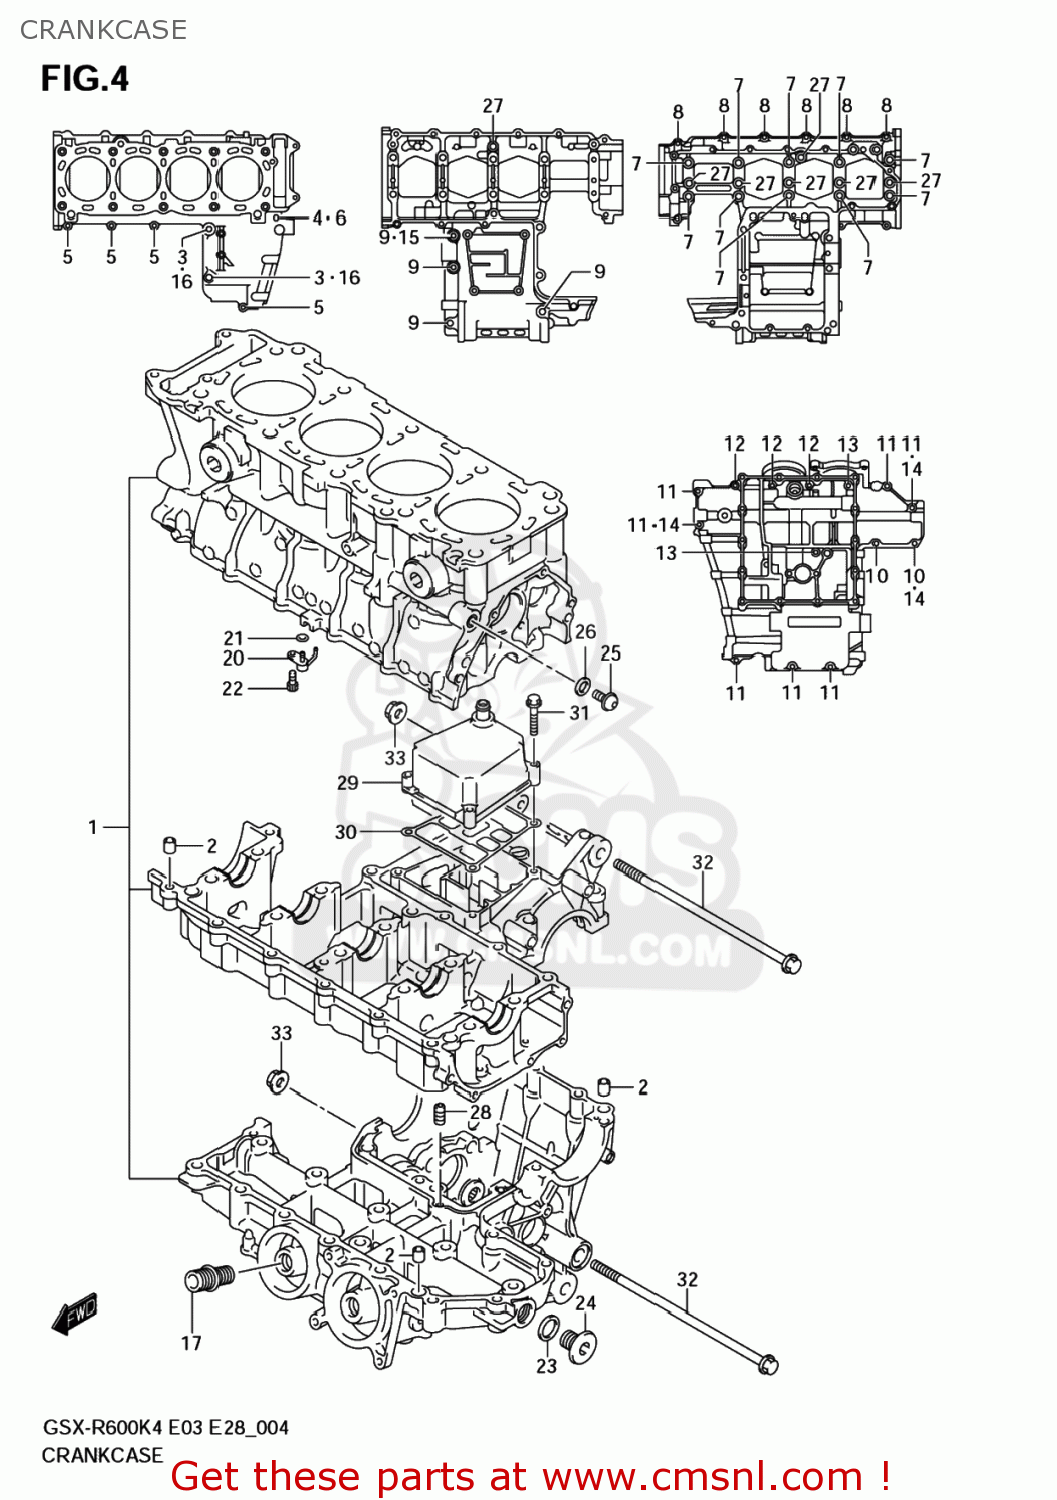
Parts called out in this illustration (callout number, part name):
1	CRANKCASE SET
2	PIN,CRANKCASE
3	BOLT(8X120)
4	GASKET(5.8X13X1.2) (NAS)
5	BOLT
6	BOLT
7	BOLT(9X95)
8	BOLT
9	BOLT
10	BOLT,G/S SWITC
11	BOLT
12	BOLT
13	BOLT
14	GASKET(5.8X13X1.2) (NAS)
15	GASKET(8.2X14X1) (NAS)
16	GASKET(8.2X14X1) (NAS)
17	UNION,OIL STAND
18	BEARING,CRANK THRUST(GREEN)
19	BEARING,CRANK THRUST(RED)
20	JET,PISTON COOLING
21	O RING(D:1.2,ID:4)
22	BOLT(6X12)
23	GASKET(16X22X2) (NAS)
24	PLUG
25	PLUG(10X10)
26	GASKET(10X14X3.6) (NAS)
27	O RING(D:1.9,ID:7.8)
28	JET(140)
29	COVER,BREATHER
30	GASKET,BREATHER COVER (NAS)
31	BOLT,G/S SWITC
32	BOLT 10X215
33	NUT
